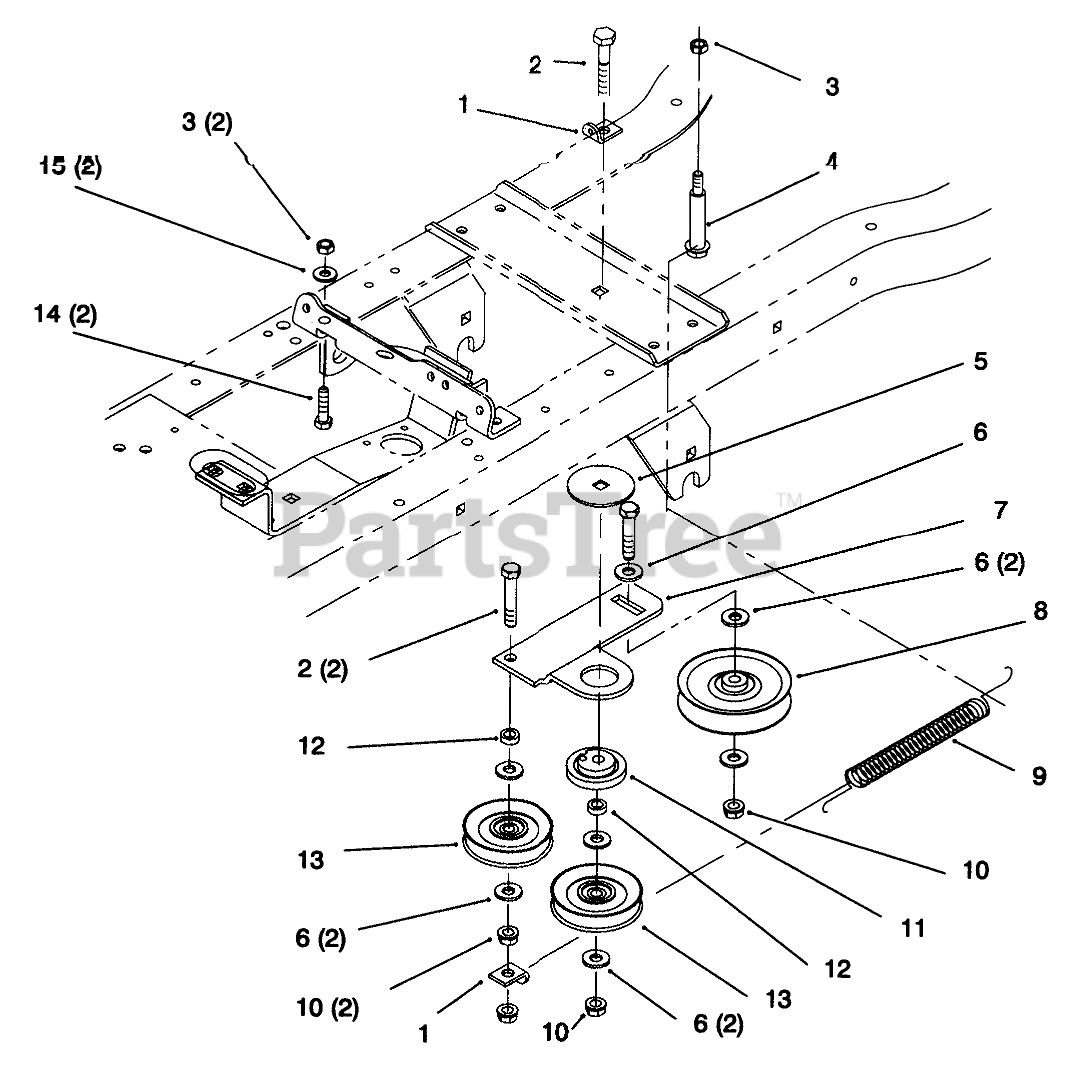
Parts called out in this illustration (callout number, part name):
1	CLIP - SPRING
2	SCREW-HH
3	NUT-LOCK, NI
4	BOLT-SHOULDER
5	WASHER-BEARING
6	WASHER-FLAT
7	ARM - IDLER
8	PULLEY-IDLER, FLAT
9	SPRING - CLUTCH
10	NUT-LOCK, NI
11	BUSHING
12	Spacer
13	PULLEY-IDLER
14	SCREW-HH
15	WASHER-PLAIN
